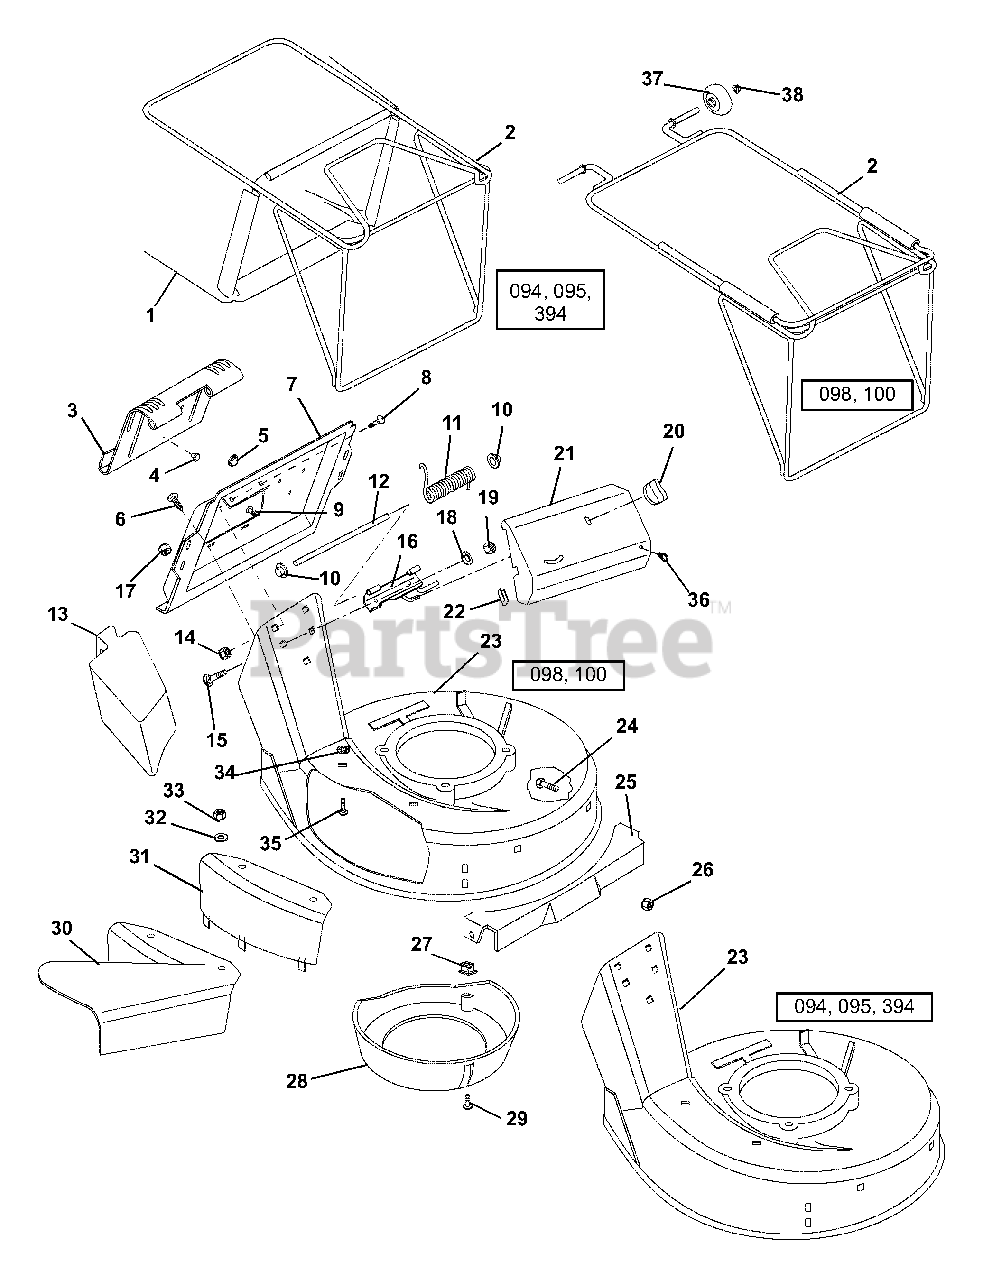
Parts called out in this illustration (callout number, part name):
1	Bag, Consumer Black (094, 095, 394)
1	Bag, Bag-N-Drag (98, 100)
2	Frame, Bagger (094, 095, 394)
2	Frame, Bag-N-Drag (098, 100)
3	Door, Catcher Plate
4	Button Bumper
6	Screw, Tapping 10-24 x .38 Pan Head
7	Plate, Catcher
8	Bolt, Round Head Square Neck .25-20 x .38
9	Screw-Tapping 12-24 x .50 Hex Washer Head (098, 100)
10	Nut, Push
11	Spring, Torsion .120 x .68 x 3.09
12	Pin, Door
13	Mulch Master Mulcher Accessory
14	Nut, Locking Flange .25-20
15	Bolt, Round Head Square Neck .25-20 x .75 Grade 5
16	Base, Hinge (098, 100)
16	Base, Hinge (095)
16	Base, Hinge (094, 394)
17	Nut, Locking Flange .25-20
18	Washer, Locking .25 x .077
19	Nut, Hex .25-20
20	Nut, Wing (098, 100)
21	Drive Cover (098, 100)
22	Trim Bumper (098, 100)
23	Mower Pan Head with Decals - Self-Propelled (094, 394)
23	Mower Pan Head with Decals - Push (095)
23	Mower Pan Head with Decals - Self Propelled (098, 100)
24	Bolt, Round Head Square Neck .31-18 x .50 Grade 5
25	Front Panel
26	Nut, Spin Lock Flange .312-18
27	Grommet, Plastic
28	Baffle, Center
29	Screw, Tapping 10-16 x .62 Hex Washer Head
30	Side Discharge Assembly (098, 100)
31	Side Discharge Cover (098, 100)
32	Washer, Flat Steel .406 x .812 x .065 (098, 100)
33	Nut, Locking Nylon .312-18 (098, 100)
34	Nut, Push .312 (098, 100)
35	Bolt, Round Head Square Neck .31-18 x .75 Grade 2 (098, 100)
36	Clip, Snap-In (098, 100)
38	Cap, .38 Rod
